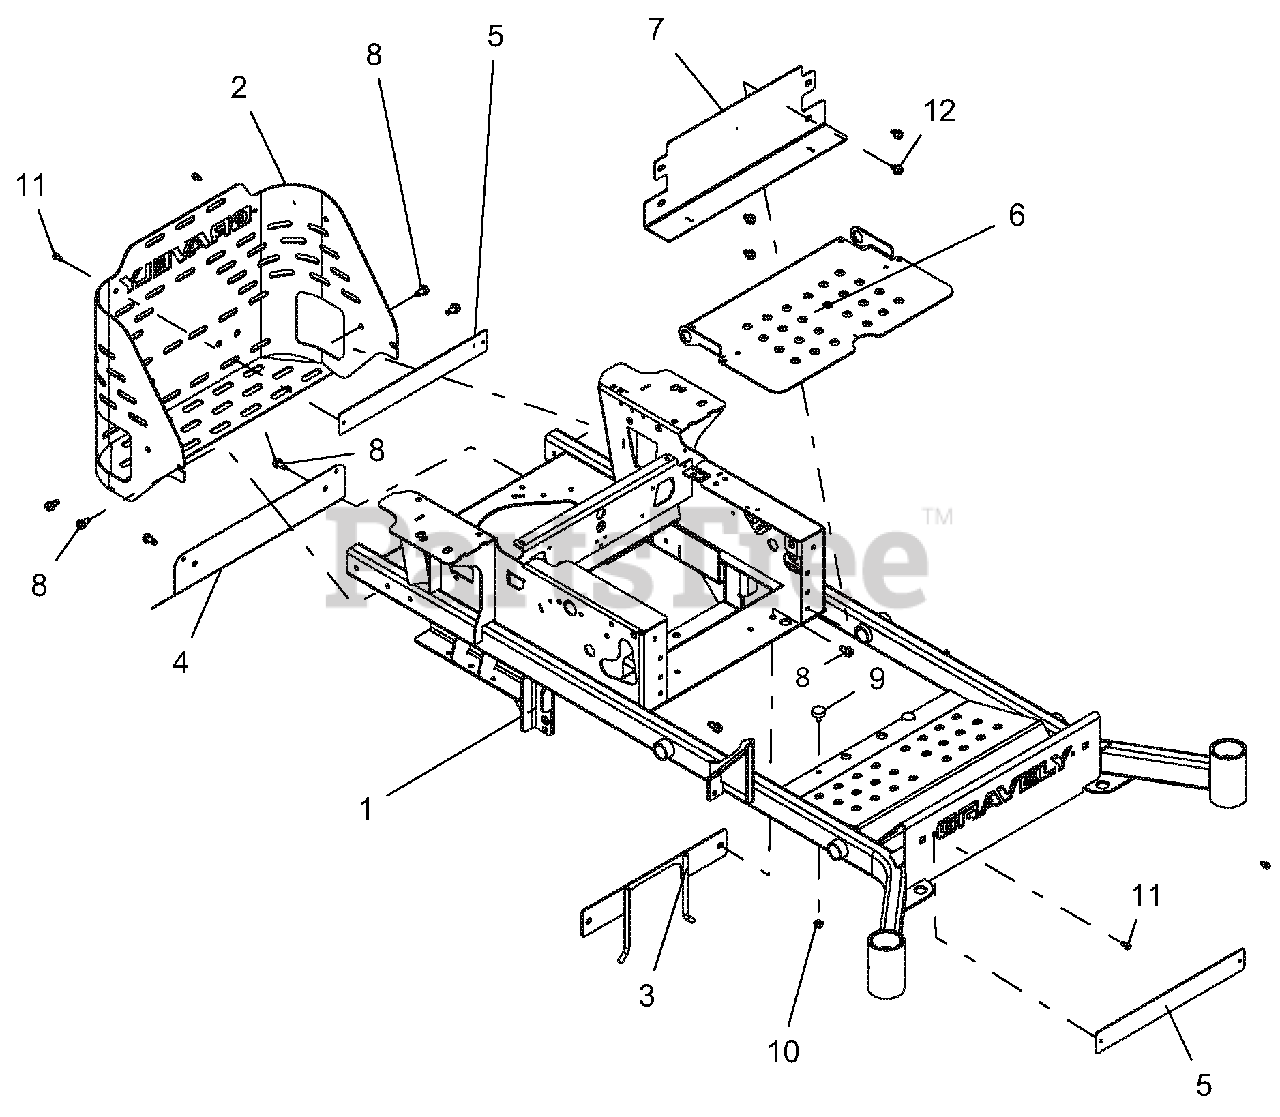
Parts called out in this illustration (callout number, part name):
1	60" MAIN FRAME W/SAFETY DECALS
2	REAR BUMPER W/SAFETY DECALS
3	WLDMT, PTO BELT FINGER-BLACK
4	SHIELD, MUFFLER HEAT
5	PLATE, BUMPER 2.00 x 16.50 - BLK
6	FOOT, PLATE W/SAFETY DECALS
7	PLATE, PT/PT100 KICK-RED
8	SCR-TAP .38-16X.75 HWH TR YWZ
9	BUMPER, RUBBER
10	@NUT-SPNLK-FLG .312-18 YWZC
11	SCR-TAP .25-20X.50 HWH TR YWZ
12	SCR-TAP .38-16X.50 HWH TR YWZ
